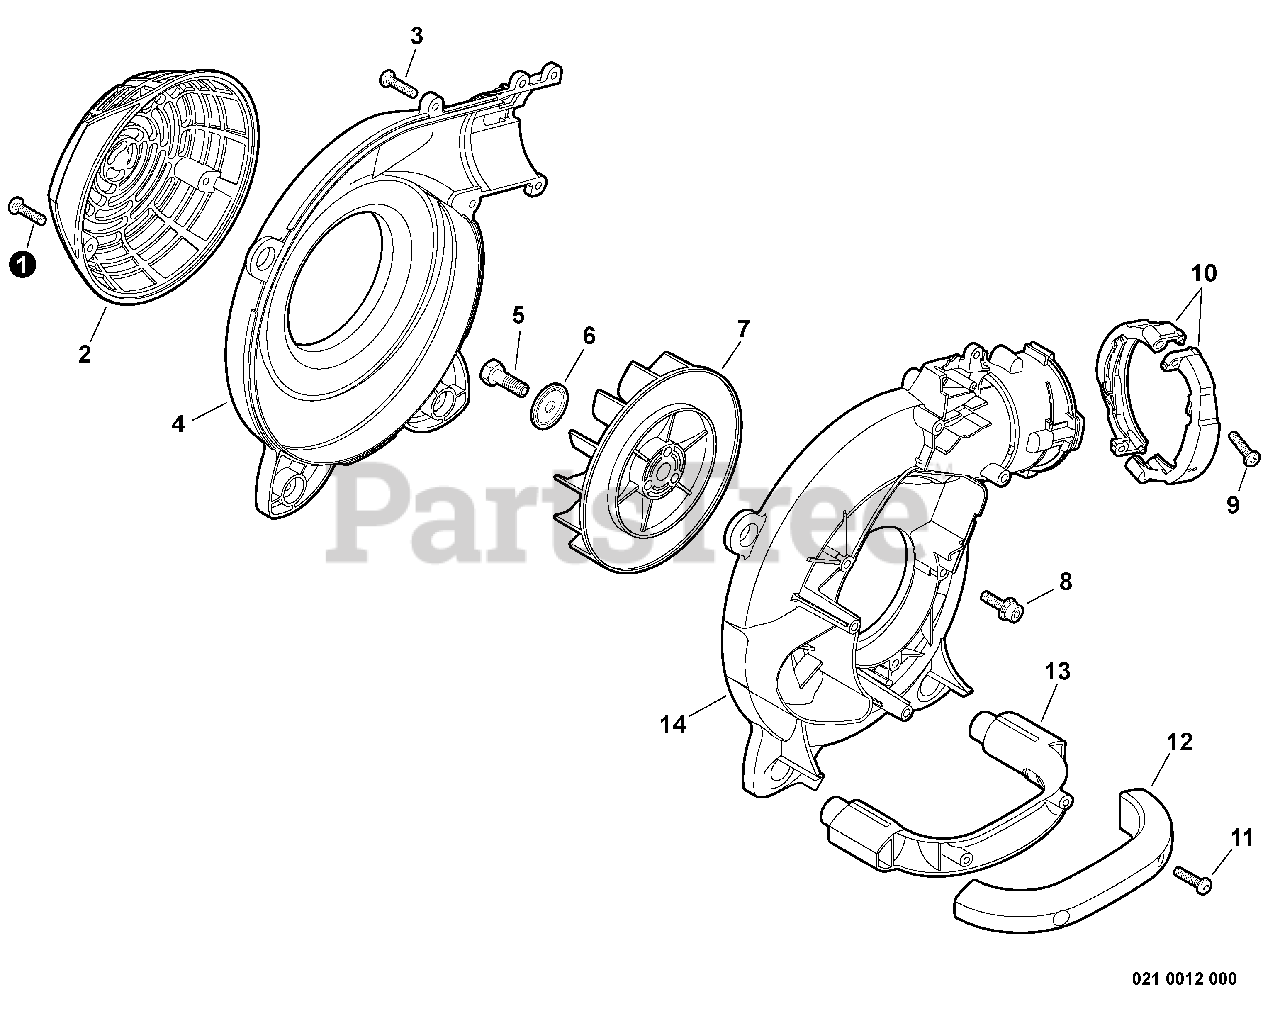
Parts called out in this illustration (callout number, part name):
1	SCREW, TAPPING 5×20
2	GUARD, DEBRIS
3	SCREW, TAPPING 5×20
4	COVER, FAN
5	BOLT 8×14
6	WASHER 8.2×31×0.8
7	FAN, BLOWER
8	BOLT 4×20
9	SCREW, TAPPING 5×20
10	COLLAR, LOCKING
11	SCREW, TAPPING 5×20
12	COVER, HANDLE
13	HANDLE, REAR
14	CASE, FAN
